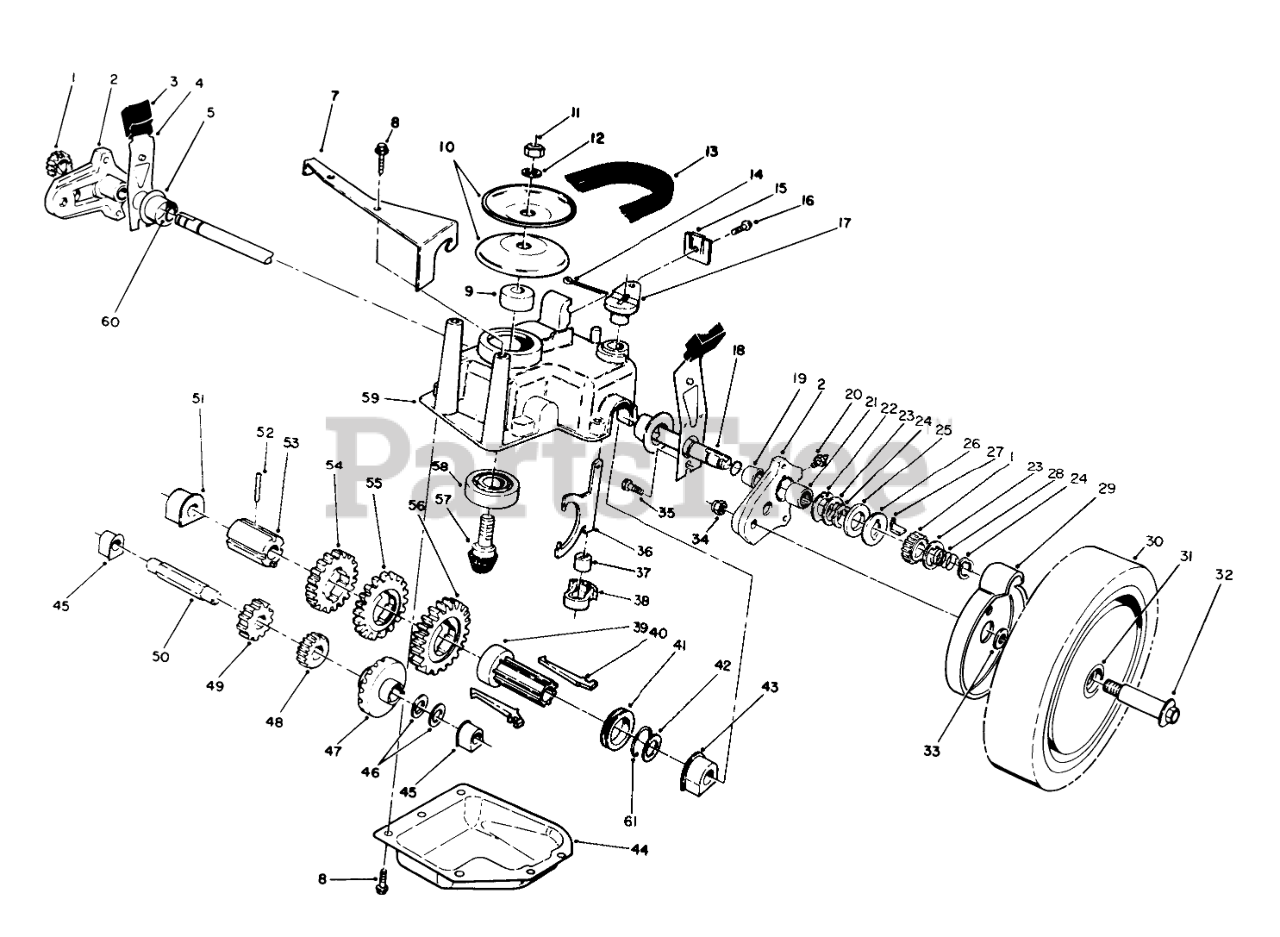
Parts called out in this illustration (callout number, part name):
1	GEAR-PINION
2	Pivot Arm Assembly (Incl. Ref #19,20, & 21)
3	KNOB-ARM
4	SPRING ARM ASM SP
5	CAP-END
7	Bracket-Guide
8	SCREW-HWHTF
9	SPACER
10	Pulley Half
11	NUT-HEX
12	WASHER-FLAT
13	V-BELT E
14	PIN-COTTER
15	Cable Clamp
16	SCREW-HWHTF
17	SHIFT LEVER
18	SHAFT-OUTPUT
19	BUSHING
20	FITTING-GREASE
21	BEARING-ROLLER
22	WASHER-ARM, PIVOT
23	WASHER-THRUST, KEYED
24	RING-CLIP, LOCKING
25	RING-FRICTION
26	WASHER-CLUTCH
27	KEY-ROCKING, LH
28	SPRING-COMPRESSION
29	COVER-WHEEL
30	Wheel-Tire & Gear Ass-y (Incl. Ref. #31)
31	BUSHING
32	WHEEL BOLT
33	SPACER-COVER, WHEEL
34	Nut
35	SCREW-HWH
36	YOKE-SHIFT
37	BUSHING-YOKE
38	RETAINER-FORK, SHIFT
39	SLEEVE-KEY, SHIFT
40	KEY-SHIFT
41	COLLAR-SHIFT
42	WASHER-PLAIN
43	BUSHING-OUTPUT
44	Cover-Gearcase
45	BUSHING
46	WASHER-THRUST
47	Gear-Bevel
48	PINION-20T
49	PINION-25T
50	SHAFT-INTERMEDIATE
51	BUSHING
52	PIN-SPRING
53	SLEEVE-GEAR
54	GEAR-39T
55	GEAR-44T
56	GEAR-49T
57	Gear-Pinion
58	BEARING-BALL
59	CASE-GEAR, UPPER
60	O-RING
61	CLIP-SPRING
